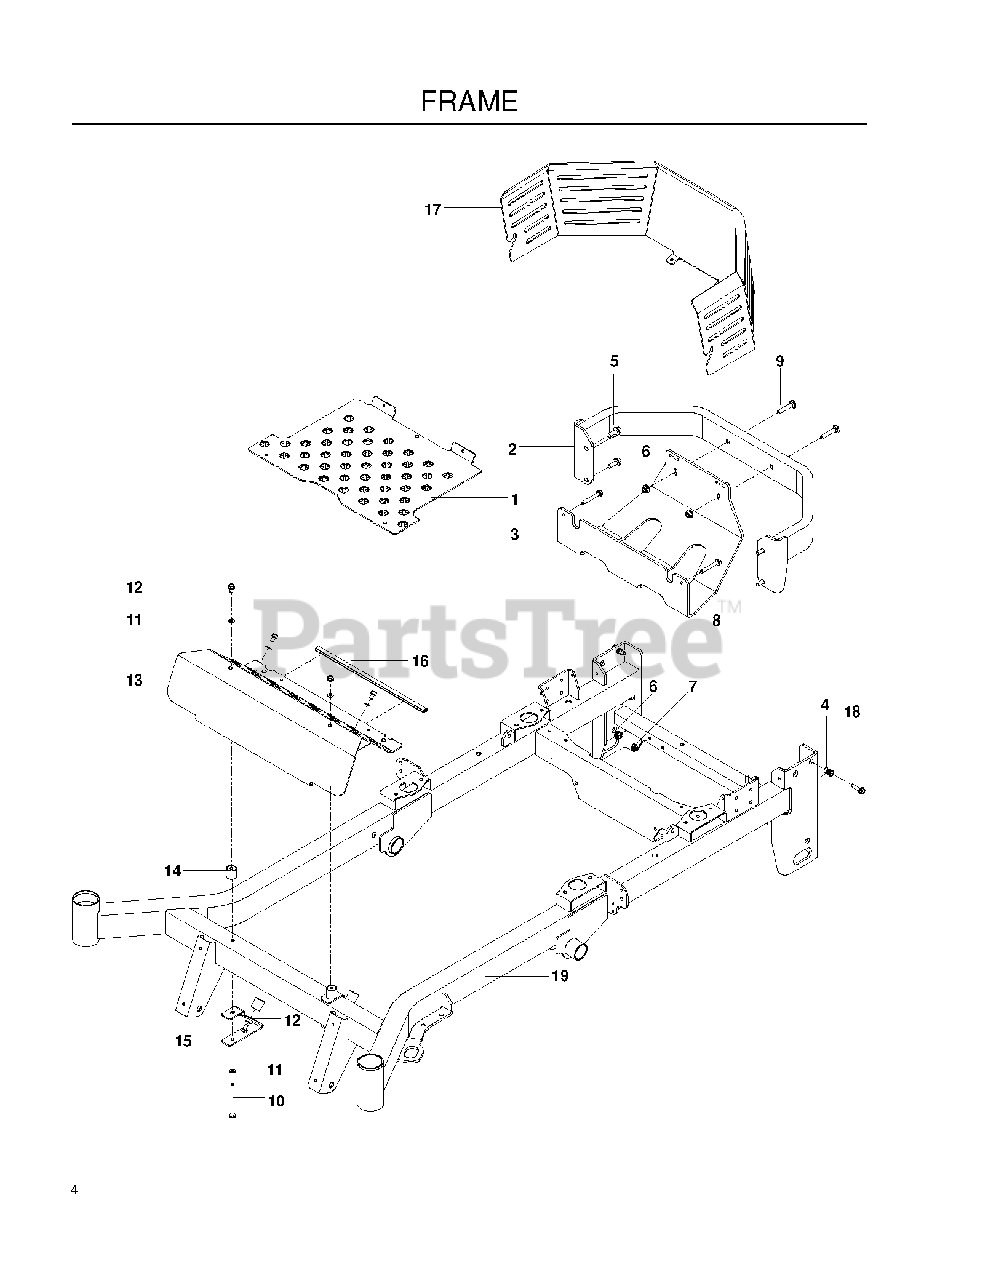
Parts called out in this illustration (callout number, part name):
1	PLATE, FLOOR PAN, BLUE
2	BUMPER, REAR, BLUE
3	PLATE, SKID, BLACK
4	NUTSERT 5/16-18 THICK GRIP
5	HHFS 3/8-16 X 1 GRD 5 ZD
6	NUT 3/8-16 HEX FLG NYLOC ZD
7	5/16-18 NYLOC FLANGE NUT
8	HHFS 5/16-18 X 2.25 GD 5
9	RHSNB 3/8C X 2
10	HHFS 5/16-18 X 3 3/4
11	WASH 5/16 DISC SPRING ZD
12	SCR 5/16-18 X 1/2 SELFTAP ZN
13	PLATE.FOOTREST.BLUE.DIXON
14	MOUNT, F/F INSERT
15	BRACKET, REST MOUNT
16	Flex Trim, 1' Black
17	GUARD, REAR, BLUE
18	HHFS 5/16-18 X 1.25 TPBLT GD 5
19	FRAME W/DECALS, GARIZZLY SE
